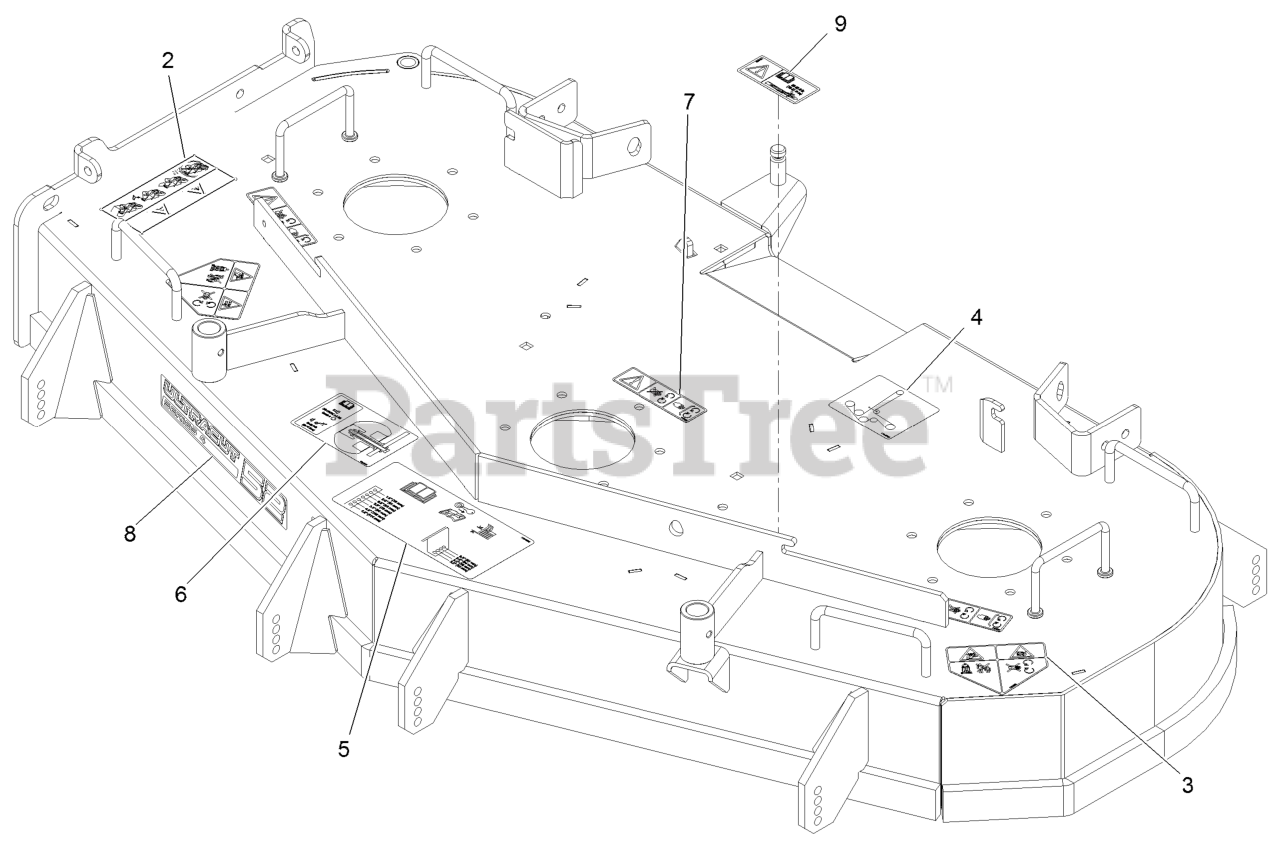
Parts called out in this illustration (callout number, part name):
2	DECAL-WARNING, BAGGER
3	DECAL-DANGER
4	DECAL-BELT ROUTING
5	DECAL-ANTI-SCALP
6	DECAL-ROLLER MOUNTING
7	DECAL-COVER, MISSING
8	DECAL, 524
9	DECAL-BOLT TORQUE
